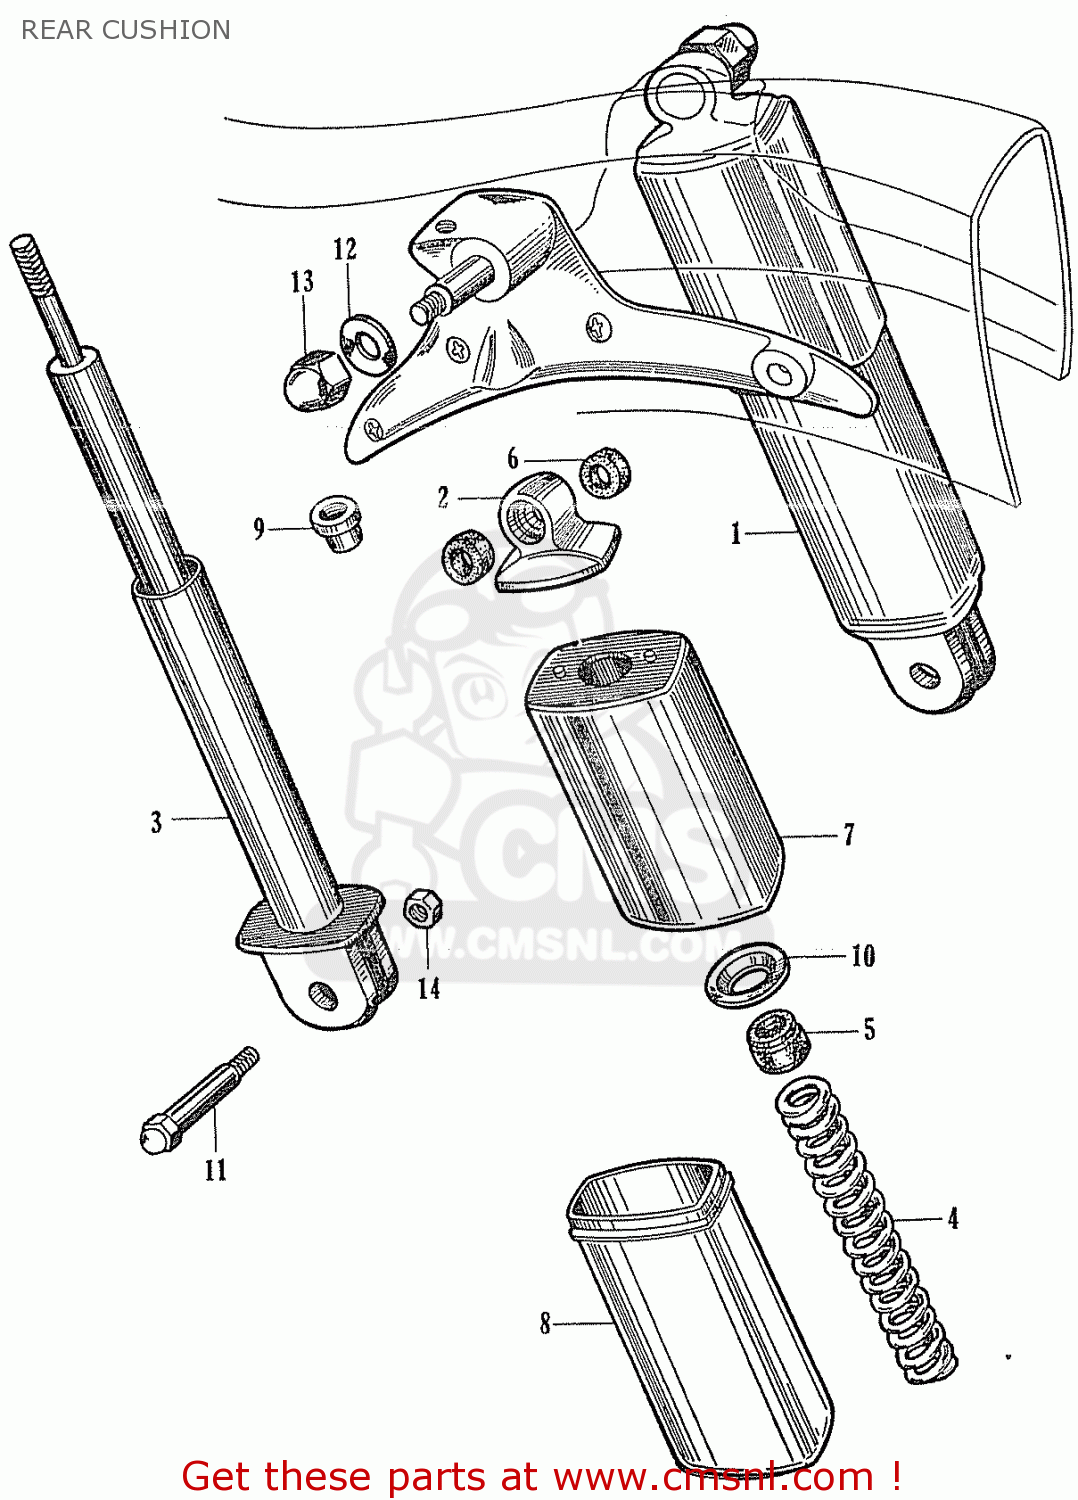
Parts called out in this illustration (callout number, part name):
1	CUSHION ASSY
2	METAL CUSHION
3	METAL CUSHION
4	SPRING CUSHION
5	RUBBER CUSHION
6	BUSH CUSHION
7	CASE CUSHION
8	CASE CUSHION
9	NUT CUSHION
10	SEAT SPRING
11	BOLT CUSHION
12	WASHER 10.3MM
13	NUT, BLIND, 10M/M
14	NUT.HEX 10MM
